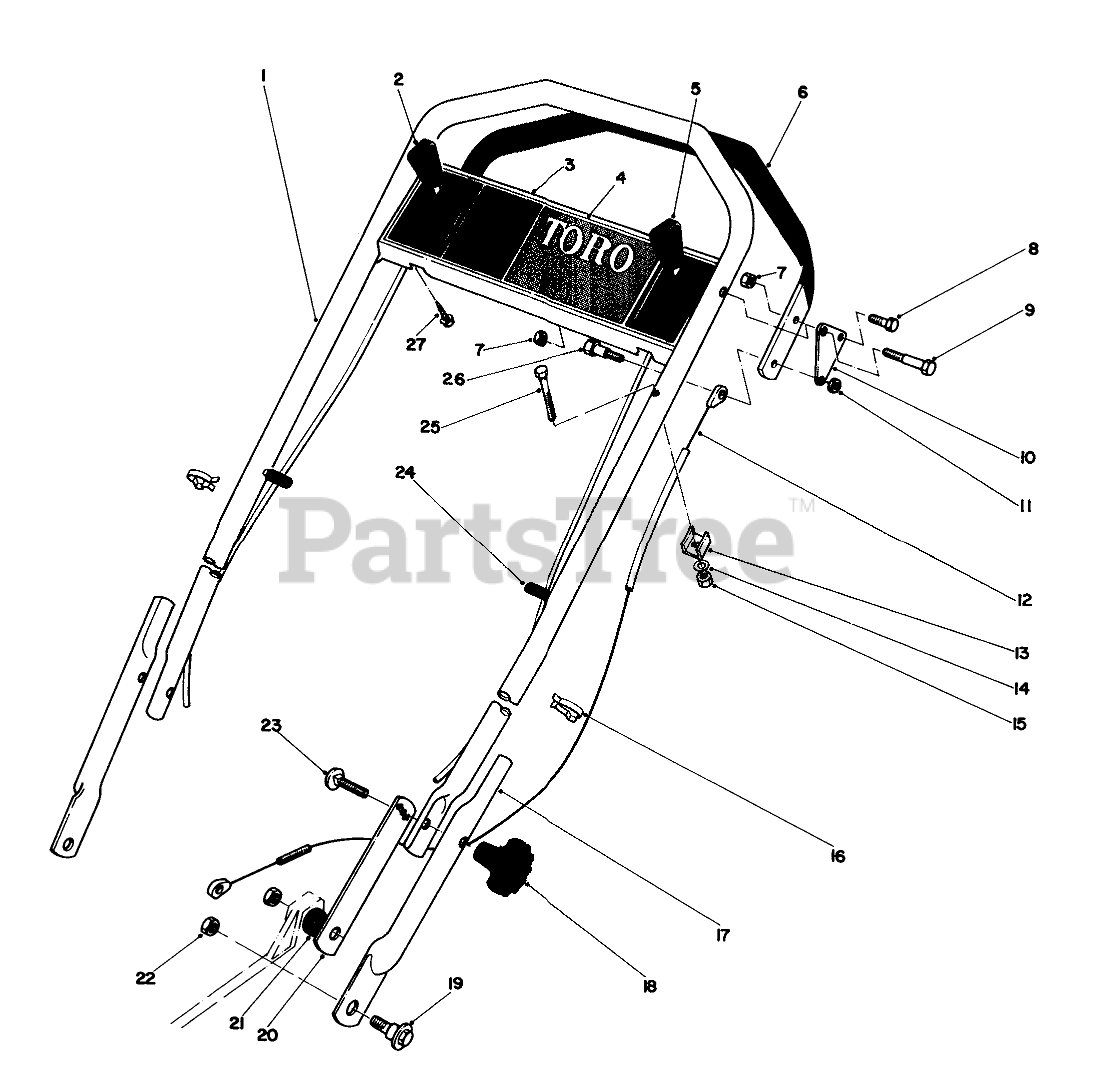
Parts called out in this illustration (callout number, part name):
1	Upper Handle
2	GROUND SPEED CONTROL
3	Control Panel (Incl. Ref. #4)
4	Decal-Control Panel (German)
5	Throttle Control
6	DEMAND HANDLE ASM
7	NUT-LOCK, CONE
8	SCREW-HH
9	BOLT-SHOULDER
10	Bracket Demand
11	NUT-HEX, SIDE DEFORM
12	DEMAND HAND CABLE
13	CLAMP-CABLE
14	WASHER-FLAT
15	NUT-LOCK, NI
16	BOWDEN CLIP
17	LOWER HANDLE
19	SCREW-SHOULDER
20	HANDLE LATCH
21	HANDLE LATCH SPACER
22	Nut
23	SCREW-CARR
24	CAP-VINYL
25	SCREW-HH
26	SHOULDER BOLT
27	SCREW-HWHTF
